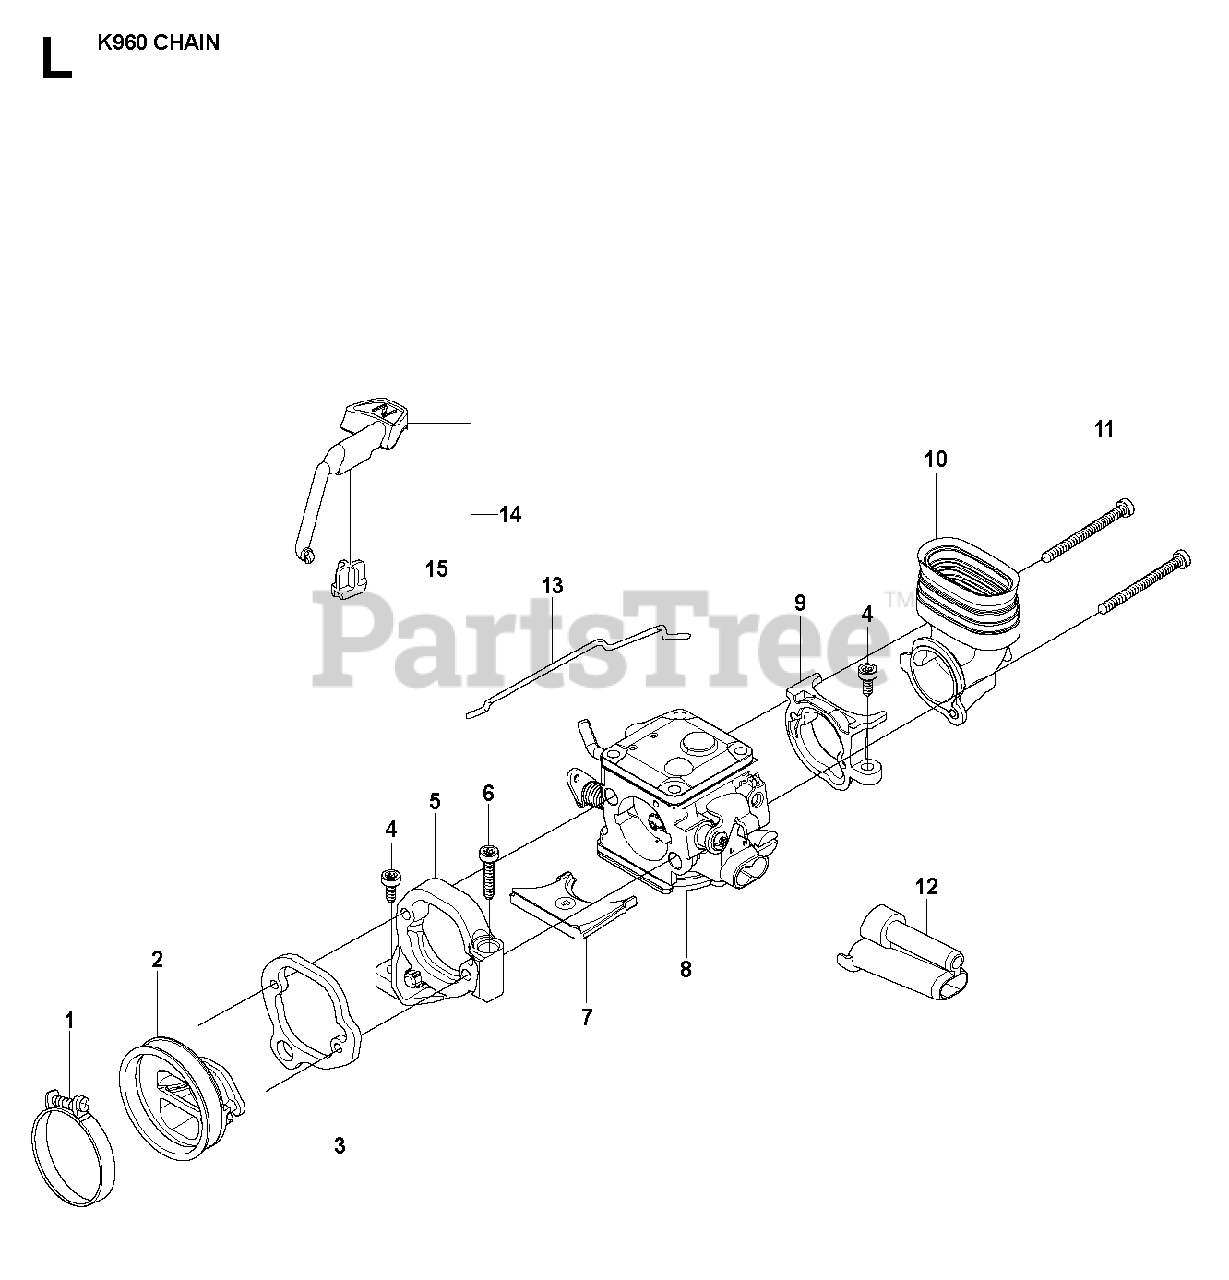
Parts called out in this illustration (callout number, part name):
1	HOSE CLAMP
4	SCREW ITXSCM
6	SCREW ITXSCM
8	CARBURETTORWalbro RWJ-3
11	SCREW ITXSCM
12	CHISEL GUIDE
13	THROTTLE ROD
14	CHOKEIncl. 15
15	WEAR PROTECTION
